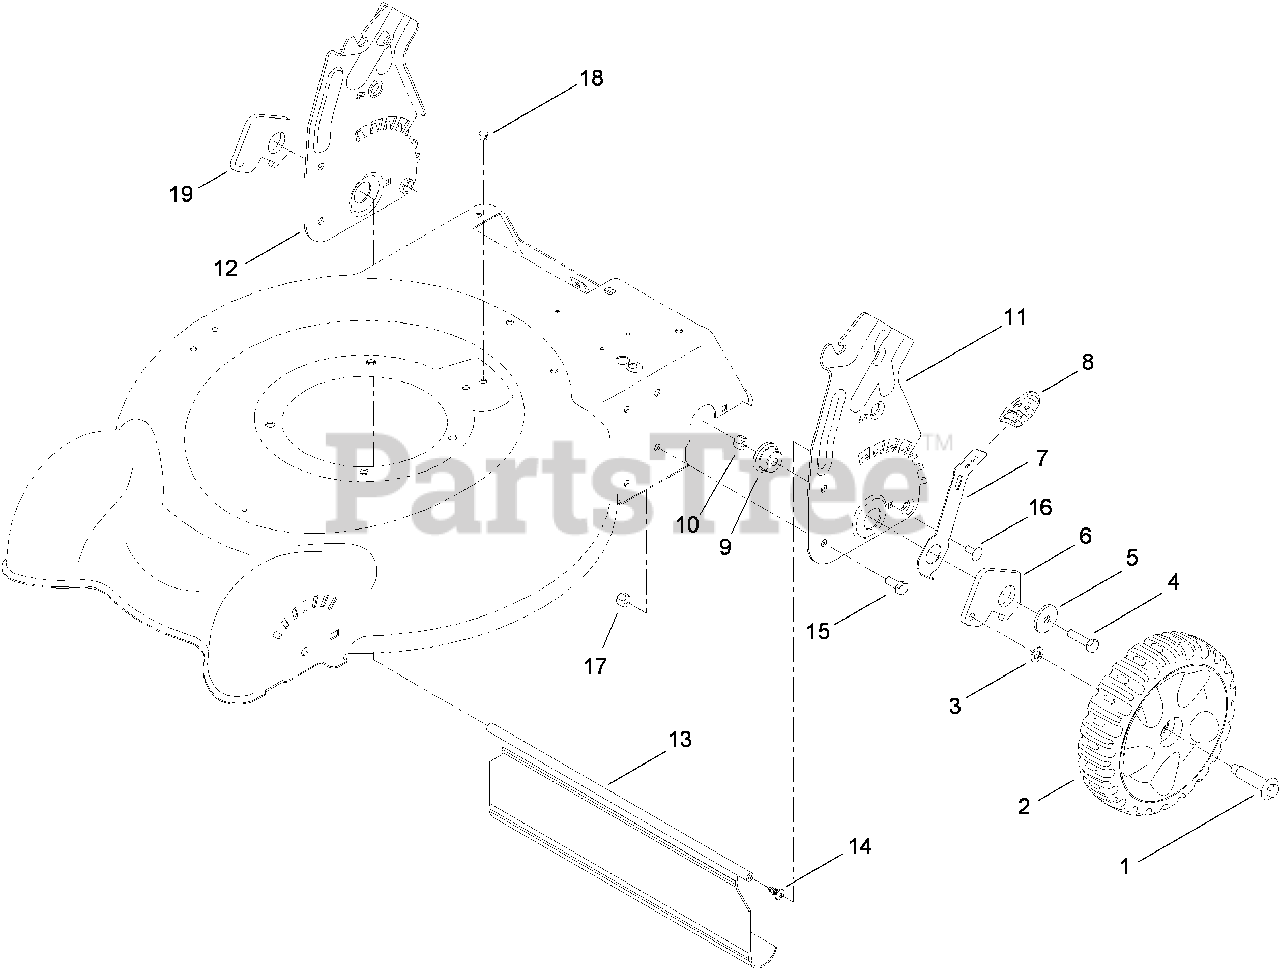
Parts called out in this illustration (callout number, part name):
1	BOLT-SHOULDER
2	8 INCH WHEEL AND TIRE ASM
4	SCREW-HH
5	Washer-Flat
6	Arm-Pivot, Rear (LH)
7	Arm-Spring
8	Knob-Lever, HOC
9	Bushing-Mount, HOC
10	NUT-LOCK, NI
11	PLATE-HOC, LH
12	PLATE-HOC, RH
13	SHIELD-TRAILING
14	SCREW-PTH
15	SCREW-HH
16	SCREW-CARR
17	NUT-LOCK, NI
18	Plug-Dome
19	ARM-PIVOT, REAR (RH)
